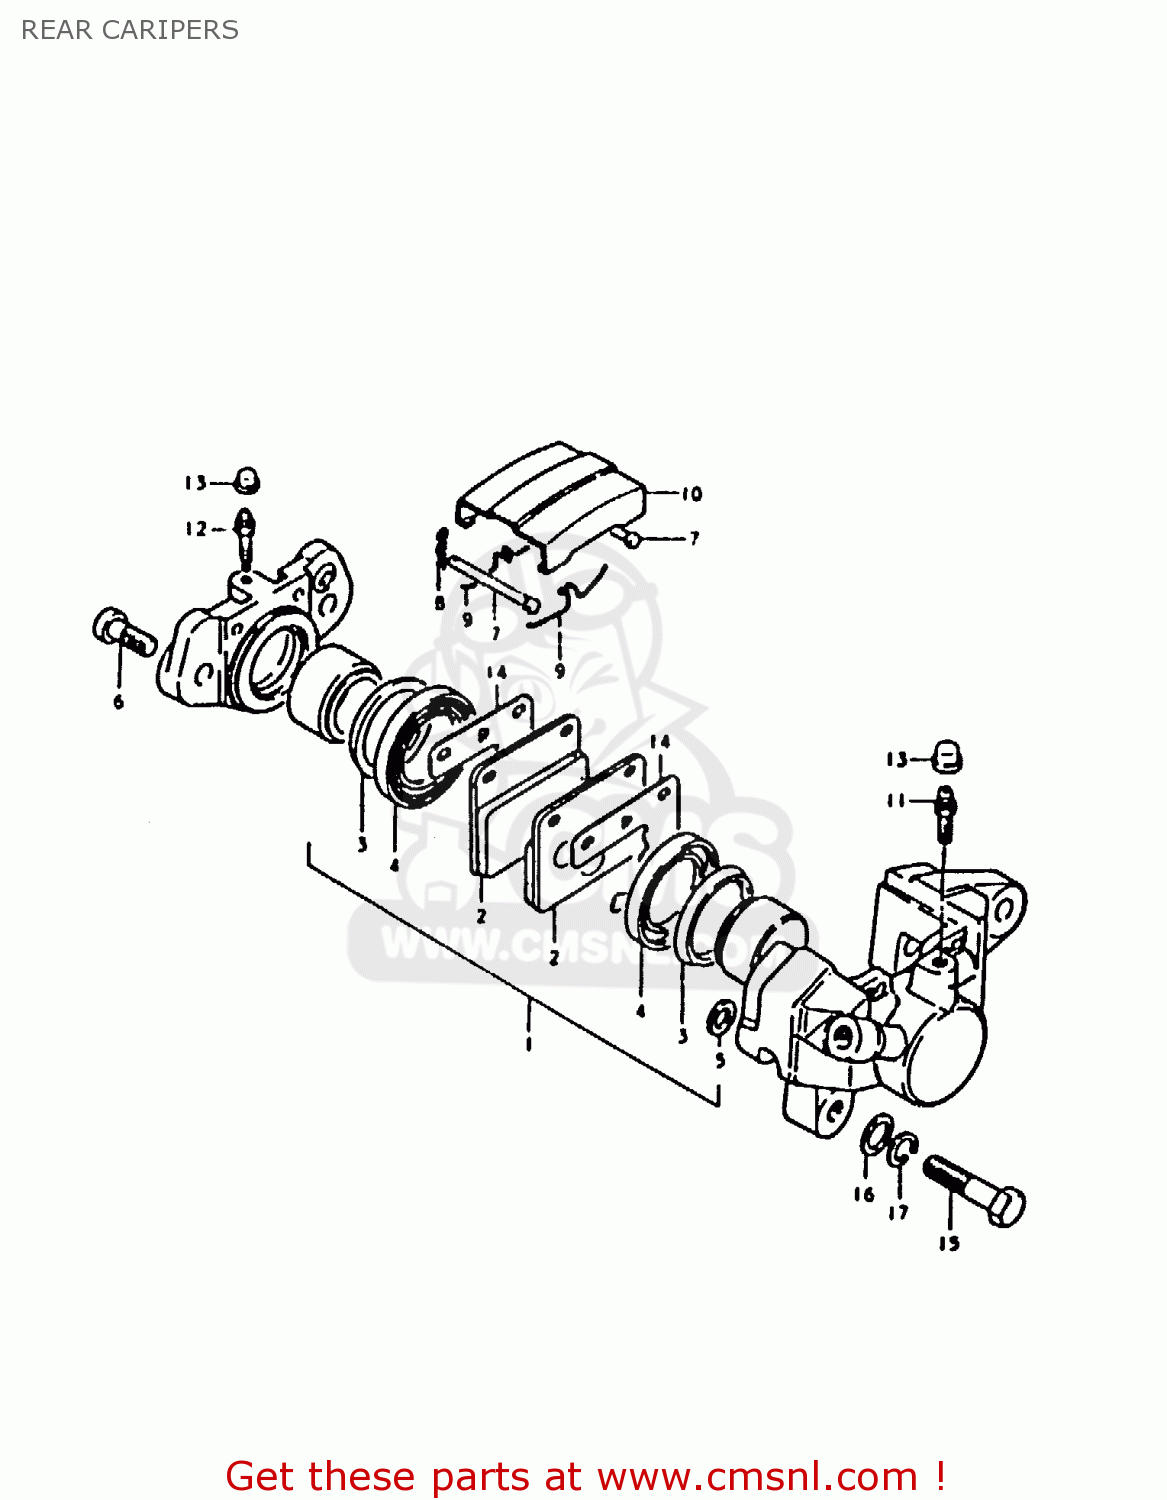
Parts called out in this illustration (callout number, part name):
1	PISTON SET
2	PAD,BRAKE
3	SEAL,PISTON
4	BOOT,PISTON
5	SEAL,PISTON
6	BOLT,HOUSING
7	PIN,PAD
8	CLIP,PAD PIN
9	SPRING
10	COVER,DUST
11	BLEEDER
12	BREATHER
13	CAP,BREATHER
14	SHIM,RR CALIPER
15	BOLT 10X34
16	WASHER
17	LOCK WASHER
